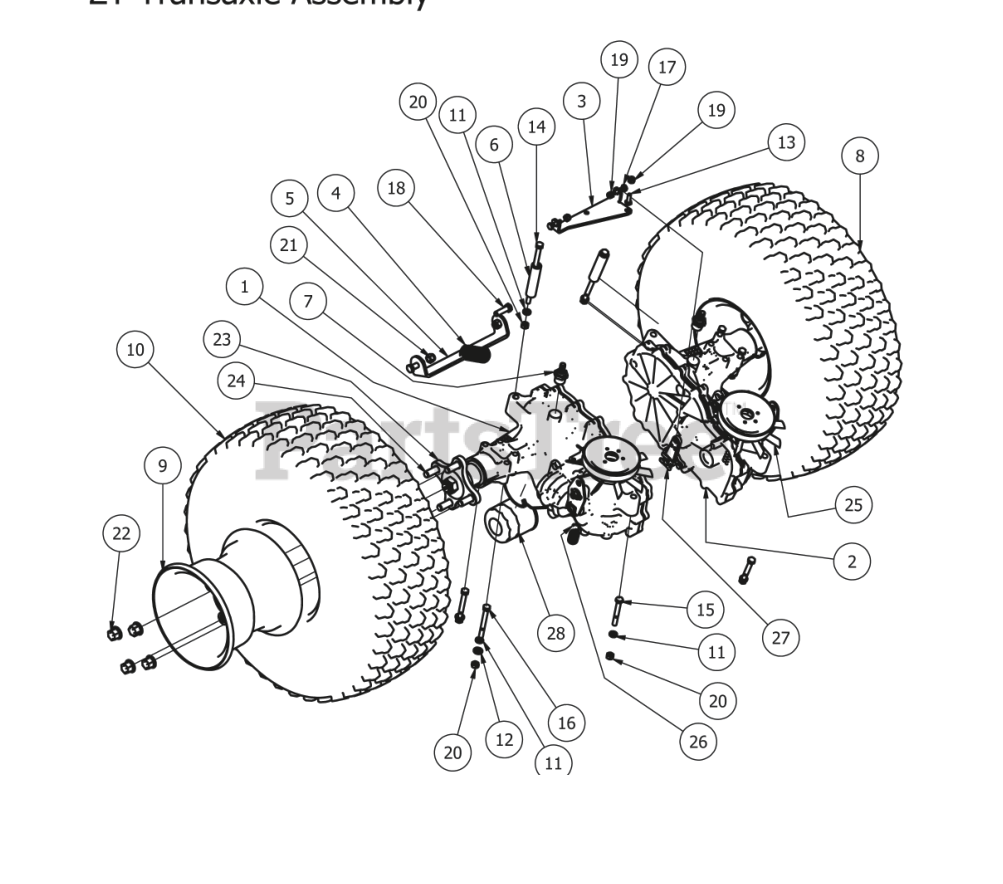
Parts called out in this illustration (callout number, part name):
1	Right ZT Transaxle
2	Left ZT Transaxle
3	ZT Crossover Brake Bracket
5	Crossover Bar for ZT
6	Transaxle Spacer
7	45 degree fitting
8	20 x 10-8 Tire and wheel Assembly
9	8 Inch Wheel
10	20X10-8 Turf Tire
11	5/16" Lock Washer
12	5/16" Flat Washer
13	1/4" x 3/4" Hex Bolt
14	5/16" x 6" Bolt
15	5/16" x 2 1/2" Bolt
16	5/16" x 3" Hex Bolt
17	Hex Bolt - UNC (Regular Thread - Inch)
18	3/8" x2" Hex Bolt
19	1/4" Nylock Nut
21	3/8 Nylock Nut
22	Acorn Lug Nut
23	ZT Transaxle Hub
24	Transaxle Wheel Studs
25	Fan/Pulley Kit
26	Transaxle Spring
27	Transaxle Brake lever
28	ZT Hydraulic Filter
